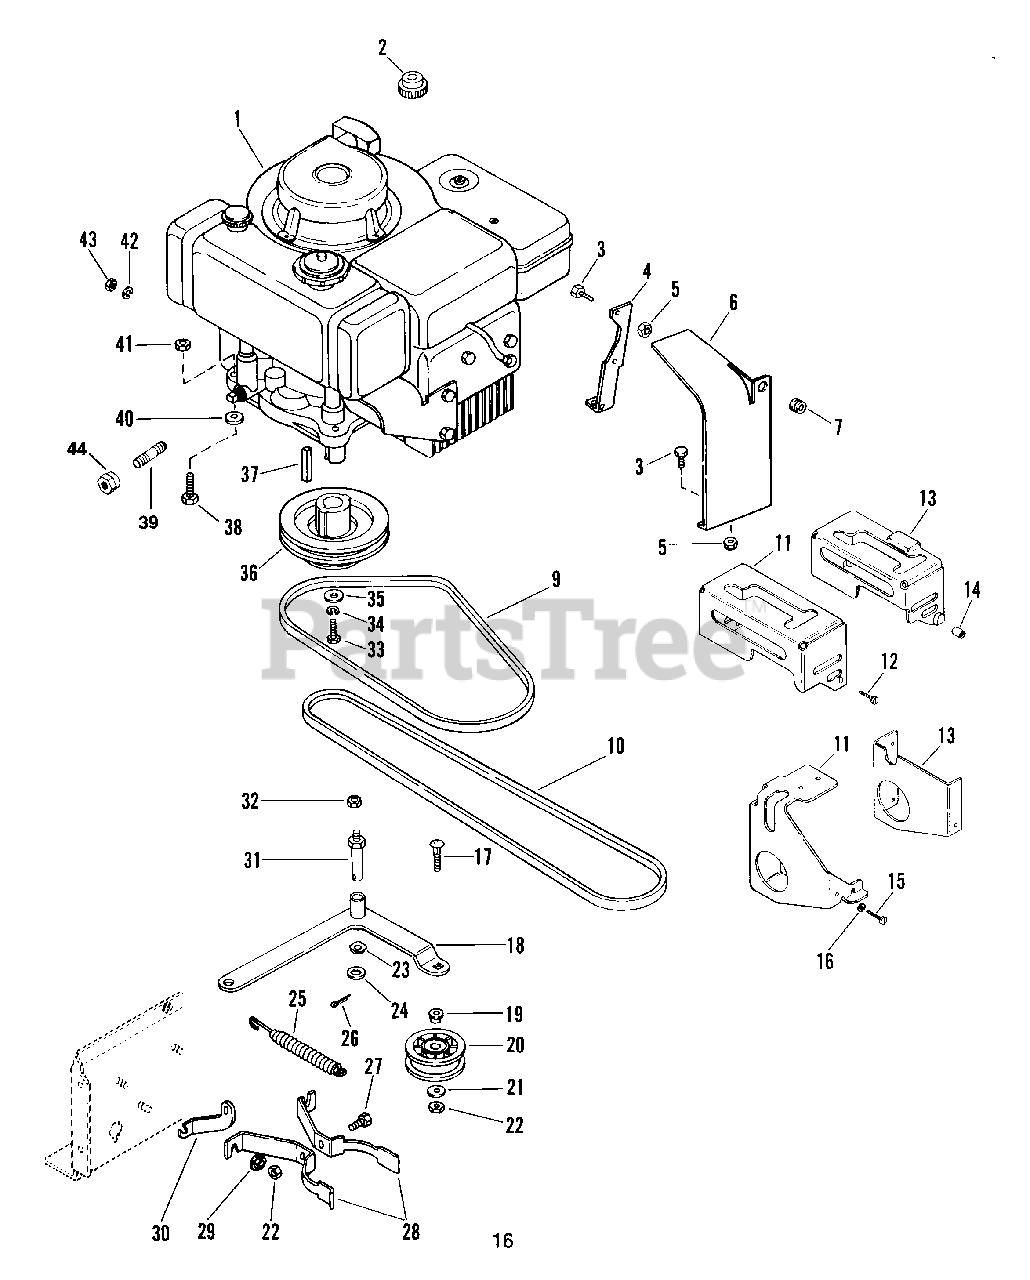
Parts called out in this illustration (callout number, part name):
1	Order Engine and Parts from EngineManufacturers Dealer
1	ENGINE- 8HP B&S
1	ENGINE 8 HP TEC ELEC. G/R BAL.
1	FC290V KAWASAKI ENGINE
1	FB460V KAWASAKI ENGINE
1	ENGINE- 12.5HP B&S I/C QUIET
1	ENGINE- B&S 11HP W/TANK
2	FUEL CAP
3	BLT-HEX .25-20X.50 PL GR2
4	BRACE
5	NUT-LK-CTR .250-20 PL
6	SHIELD
7	GROMMET, .31 ID
9	V-BELT, 3L-RAW EDGE
10	V-BELT, HA-RAW EDGE
10	V-BELT, 4L-RAW EDGE
11	HEAT SHIELD
12	SCR-TAP 10-12X1.25 CROVH PL A
13	HEAT DEFLECTOR
14	SPACER .288X.438X.600
15	SCR-TAP 10-12X.50 CRPH PL A
16	WSHR-FL-STL .194X.492X.047 PL
17	BLT-RDHDSQNK .31-18X1.25 SHTPL
18	IDLER ARM
19	BSHG-FLG .344X.468X.485X.750
20	IDLER-FLAT 2.56 X .47 CLARK
21	WSHR-FL-STL .323X.625X.062 PL
22	NUT-LK .312-18 GR A PL
23	WAVE WASHER .531X.781X.125FH
24	WSHR-FL-STL .505X.875X.024 PL
25	SG-TENS .062X.72X6.65 WLD 7
26	PIN-COTR .09X.75 PL
27	BLT-HEX .31-18X.75 PL GR2
28	BELT FINGER
29	NUT-FLG. .312-18 PL
30	BELT FINGER BRACE
31	SHOULDER STUD
32	NUT-LK-CTR .375-16 GR A PL
33	BLT-HEX .44-20X1.25 GR5
33	BLT-HEX .38-24X1.25 BLKO GR5
33	BLT-HEX M10 X 1.5X28
34	WSHR-LK .375X.115 HVY PL
34	WSHR-LK .438X.133 HVY
35	WSHR-FL-STL .505X1.140X.250
36	ENGINE SHEAVE
37	KEY-STR .25X2.0X.25
38	BLT-HEX .31-18X1.50 PL GR5
38	BLT-HEX M 8MM-1.25X25MM
39	NIPPLE
40	WSHR-FL-STL .328X.875X.062 PL
41	NUT-LK-TOP .312-18 GR C PL
42	WSHR-LK .313X.078 PL MED
43	NUT M (ND)
44	PIPE CAP
